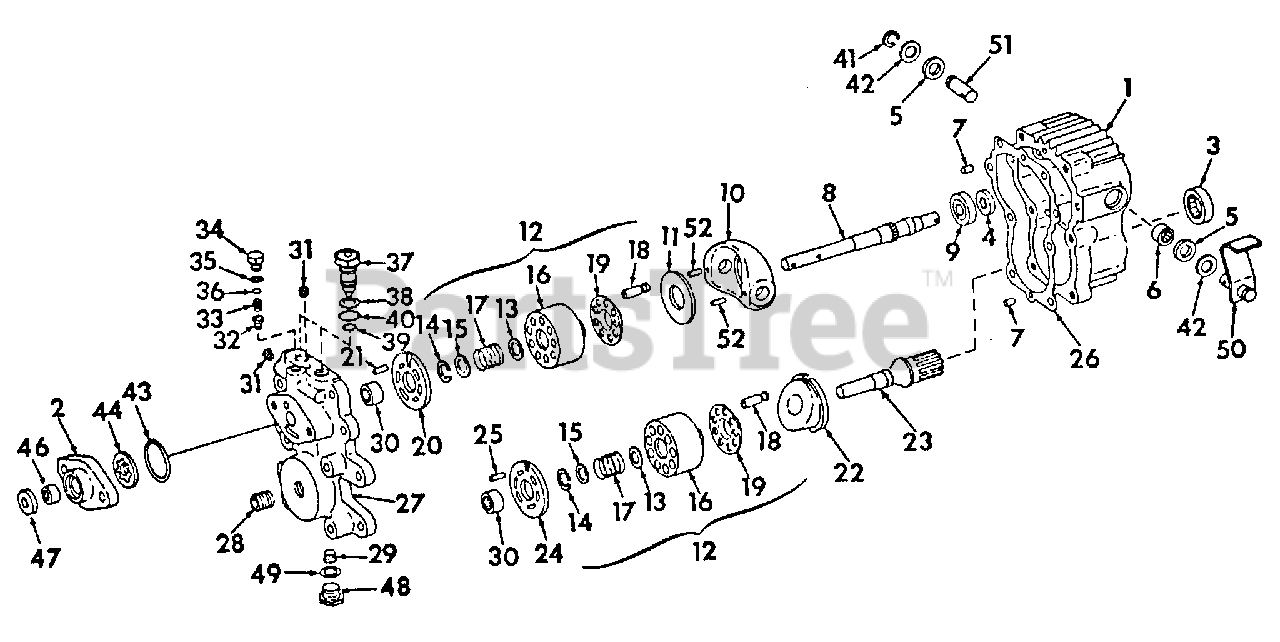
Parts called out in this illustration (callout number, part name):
1	Housing Assy
2	Housing, Charge Pump
3	Bearing, Hyd Pump Shaft Roller
4	Seal, Lip
5	Seal, Lip
6	Bearing, Needle
7	Pin, Transmission Housing
8	Shaft, Transmission Hyd Pump
9	Bearing, Ball
10	Swashplate, Hyd Pump
11	Plate, Hyd Pump Swashplate Thrust
12	Kit, Cylinder Block Motor & Pump
13	Washer, Spring Front
14	Ring, Hyd Cylinder Block Spring Rear Washer Snap
15	Washer, Hyd Cylinder Block Spring Rear
16	Block, Cylinder
17	Spring, Hyd Cylinder Block
18	Piston Assy, Hyd Pump & Motor
19	Retainer, Hyd Piston Slipper
20	Plate, Hyd Cylinder Block Valve
21	Pin, Hyd Pump Cylinder Block
22	Swashplate, Hyd Motor
23	Shaft, Transmission Hyd Motor
24	Plate, Hyd Motor Cylinder Block Valve
25	Pin, Hyd Motor Cylinder Block
26	Gasket, Transmission Housing
27	Housing, Center Section
28	Fitting, Center Housing
29	Plug, 1/4-18 Automotive Hex Soc Hd Pipe
30	Bearing, Center Housing Needle
31	Plug, 1/8-27 Automotive Hex Soc Hd Pipe
32	Cone, Charge Pump Relief Valve
33	Spring, Charge Pump Relief Valve
34	Plug, Charge Pump Relief Valve
35	O-Ring, 13/32 X 9/16 X 5/64 Relief Valve Plug
37	Valve Assy, Center Housing Check
38	Washer, Check Valve Housing
39	O-Ring, 5/8 X 3/4 X 1/16
40	O-Ring, 3/4 X 15/16 X 3/32 Check Valve Housing Large
41	Ring, Trunnion Shaft Snap
42	Washer, Trunnion Shaft Seal Retaining
43	O-Ring, 2-3/8 X 2-1/2 X 1/6 Class 5
44	Rotor Assy, Charge Pump
46	Bearing, Charge Pump Housing Needle
47	Seal, Lip
48	Plug, 3/4-16 C-Z Str Thd
49	O-Ring, 41/64 X 13/16 X 3/32
50	Shaft Assy, Trunnion
51	Shaft, Trunnion
52	Pin, 3/16 X 5/8 Coiled Spring
